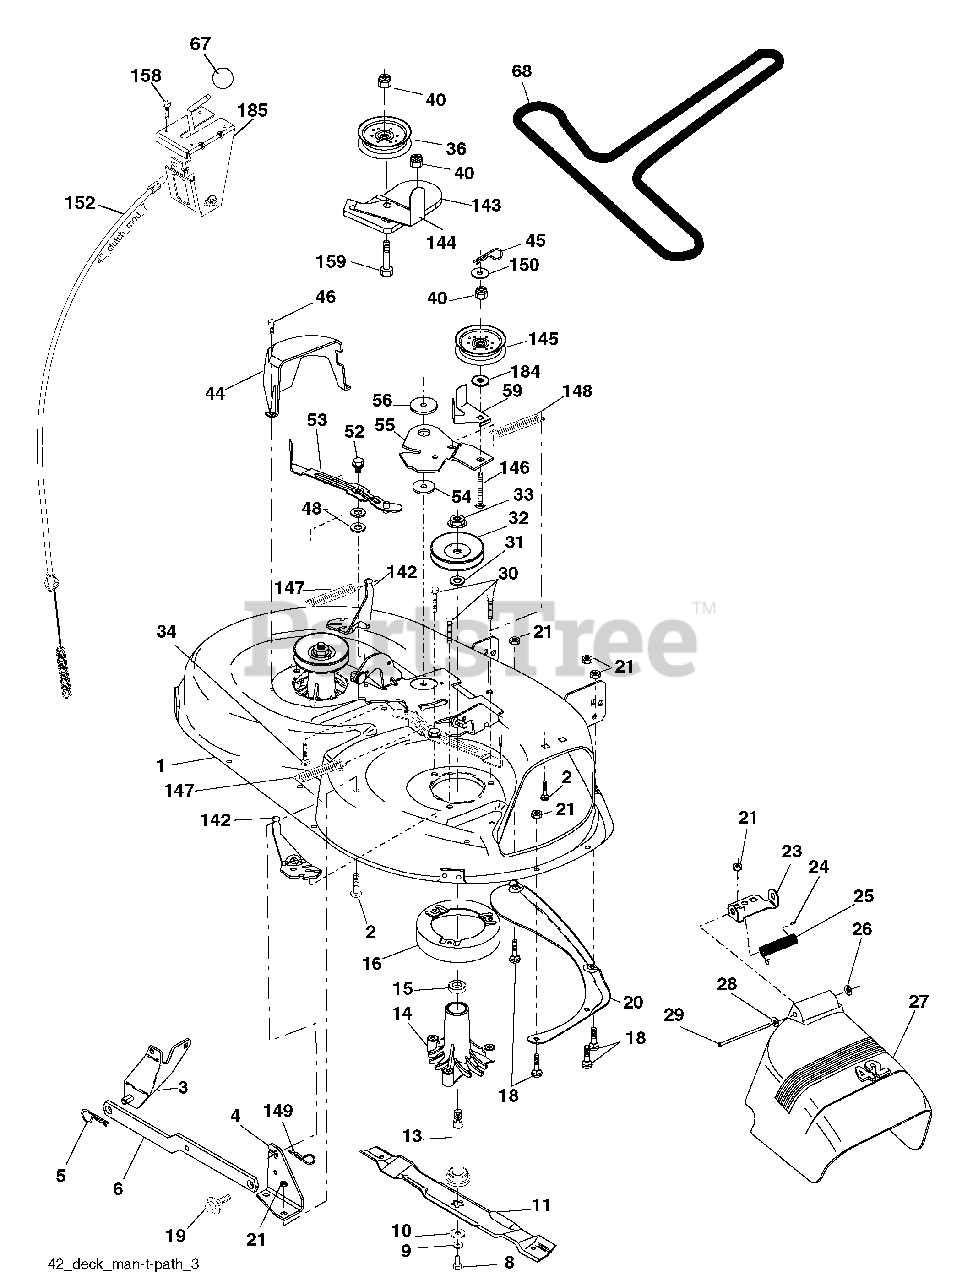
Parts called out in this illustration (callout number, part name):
1	Mower Deck Assembly, 42"
2	Bolt
3	Bracket Asm Fr. Sway Bar 3/42
4	Bracket Asm Deck 42" Sway Bar
5	Retainer Spring
6	Bar Sway Deck
8	Bolt 3/8-24 x 1.25 Gr. 8 Patched
9	Washer, Lock
10	Washer, Hardened (The following Blades are available)
11	Blade Mower 42” Hi-Lift (for bagging and discharging)
11	Blade, Mulching 42” Std (for mulching mowers only)
11	Blade Mulching 42” Premium (For better wear when mulching)
13	Shaft As sem bly, Mandrel, Vented
14	Housing, Mandrel, Vented
15	Bearing, Ball, Mandrel
16	Stripper, Mandrel Deck
18	Bolt, Carriage 5/16-18 x 5/8
19	Bolt, Shoulder
20	Baffle, Vortex
21	Nut
23	Bracket, Deflector Mower 42"
24	Cap, Sleeve 80 x 112 Blk Mower
25	Spring, Torsion, Deflector 2 52
26	Nut, Push Phos & Oil
27	Shield, Deflector 42" Blk
28	Washer 11/32 x 5/8 x 16 Ga.
29	Rod, Hinge 42" 6 75 W/G
30	Screw Thdrol
31	Washer, Spacer Mower Vented
32	Pulley, Mandrel
33	Nut, Toplock
34	Bolt Carr SH 3/8-16 x 1-1/2 Gr.5
36	Pulley, Idler, Flat
40	Nut Lock 3/8-16
44	Guard, Mandrel, LH
45	Retainer
46	Screw, Thdrol 1/4-20 x 5/8 T
48	Washer, Hardened
52	Bolt, Shoulder 5/16-18 unc
53	Arm Assembly, Pad, Brake
54	Washer, Hardened
55	Arm, Idler
56	Spacer, Retainer
59	Guard TUV Idler
67	Knob Round
68	V-Belt, 42" Mower
142	Arm Spring Brake Mower
143	Bracket Arm Idler 42"
144	Keeper Belt 42" Clutch Cable
145	Pulley Idler Flat
146	Bolt Carriage Idler
147	Spring Extension
148	Spring Return Idler
149	Retainer Spring Yellow
150	Washer 9/32 x 3/4 x 10 Ga.
152	Clutch Cable 42"
158	Screw Hex Thd Cut 1/4-20 x 1/2
159	Bolt Rdhd Sqn 3/8-16 unc x 1-3/4
184	Washer 13/32 x 7/8 x 10 Ga.
185	Head Asm Cable Clutch
185	Mandrel Assembly
185	Replacement Mower, Complete
